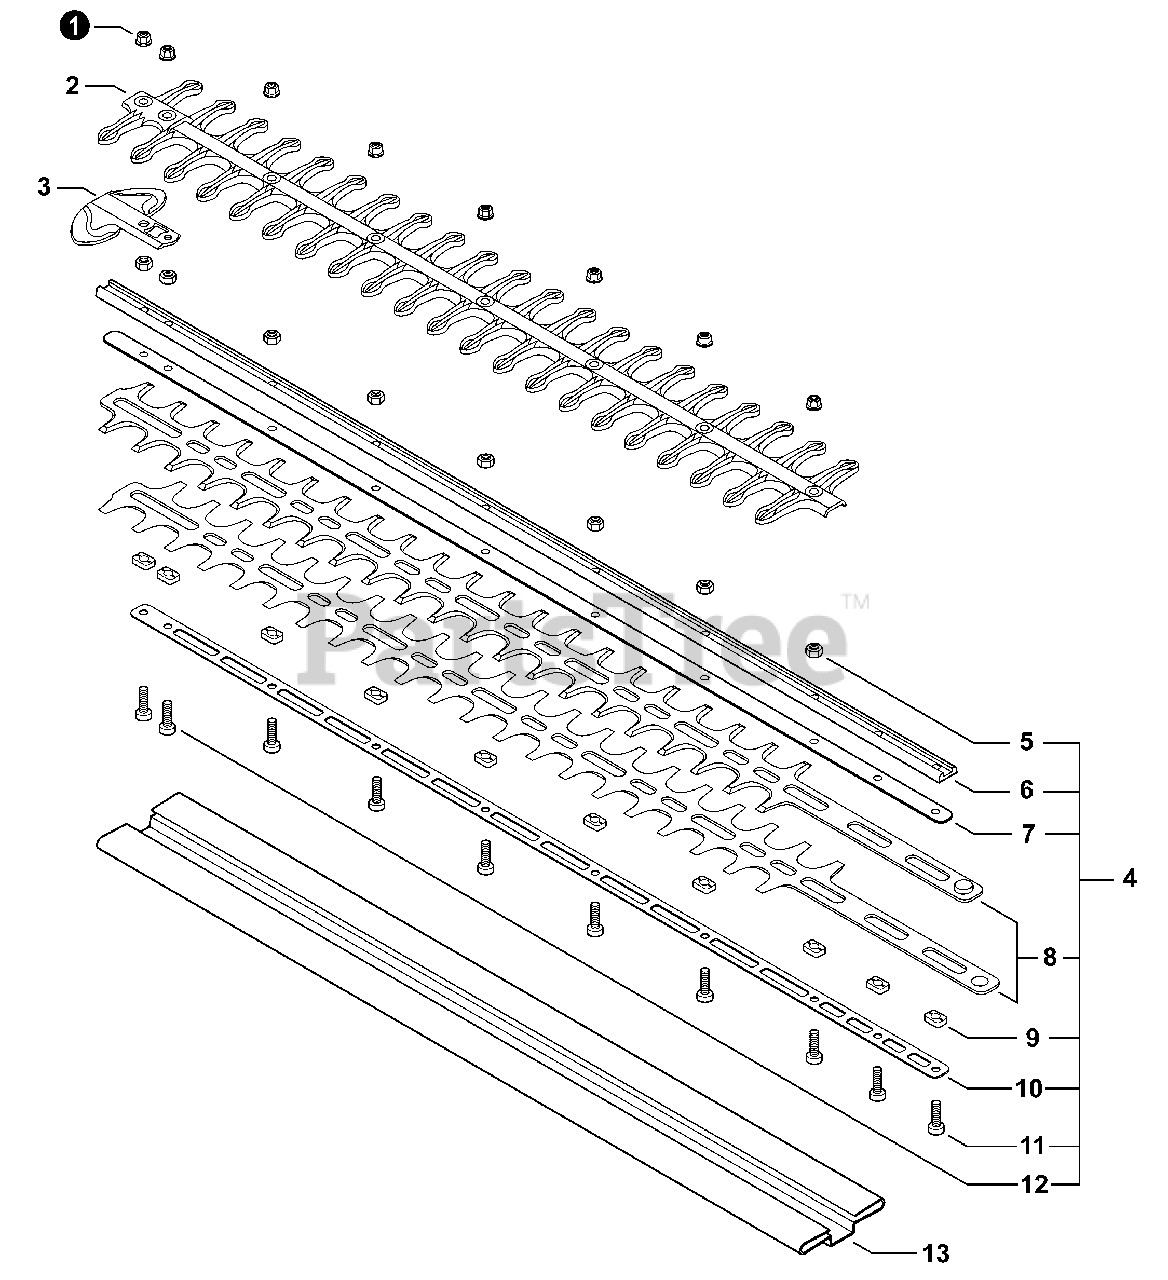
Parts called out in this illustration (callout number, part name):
1	NUT, FLANGE M5
2	PROTECTOR
3	GUARD, TIP
4	CUTTER ASSY, 24"
6	SUPPORT, CUTTER 24"
7	PLATE, CUTTER 24"
8	CUTTER 24"
10	SUPPORT, CUTTER 24"
11	BOLT, TORX 5×20
12	BOLT, TORX 5×25
13	SCABBARD
